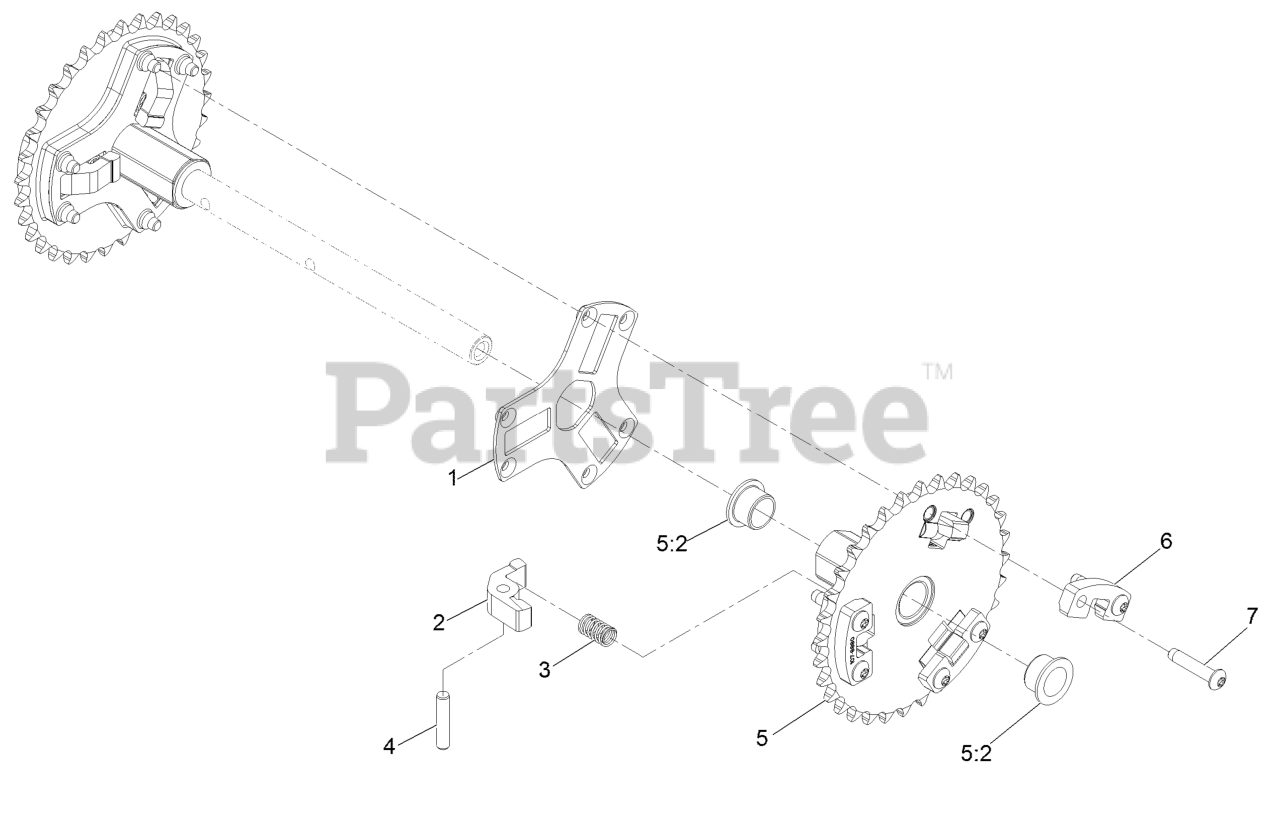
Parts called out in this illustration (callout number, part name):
1	Retainer-Pawl Pin
2	Pawl-Clutch
3	Spring-Compression
4	Pin-Dowel
5	32T Sprocket ASM
5:2	Bushing-Flange
6	Support-Pawl
7	Screw-TTH, Thread Rolling
